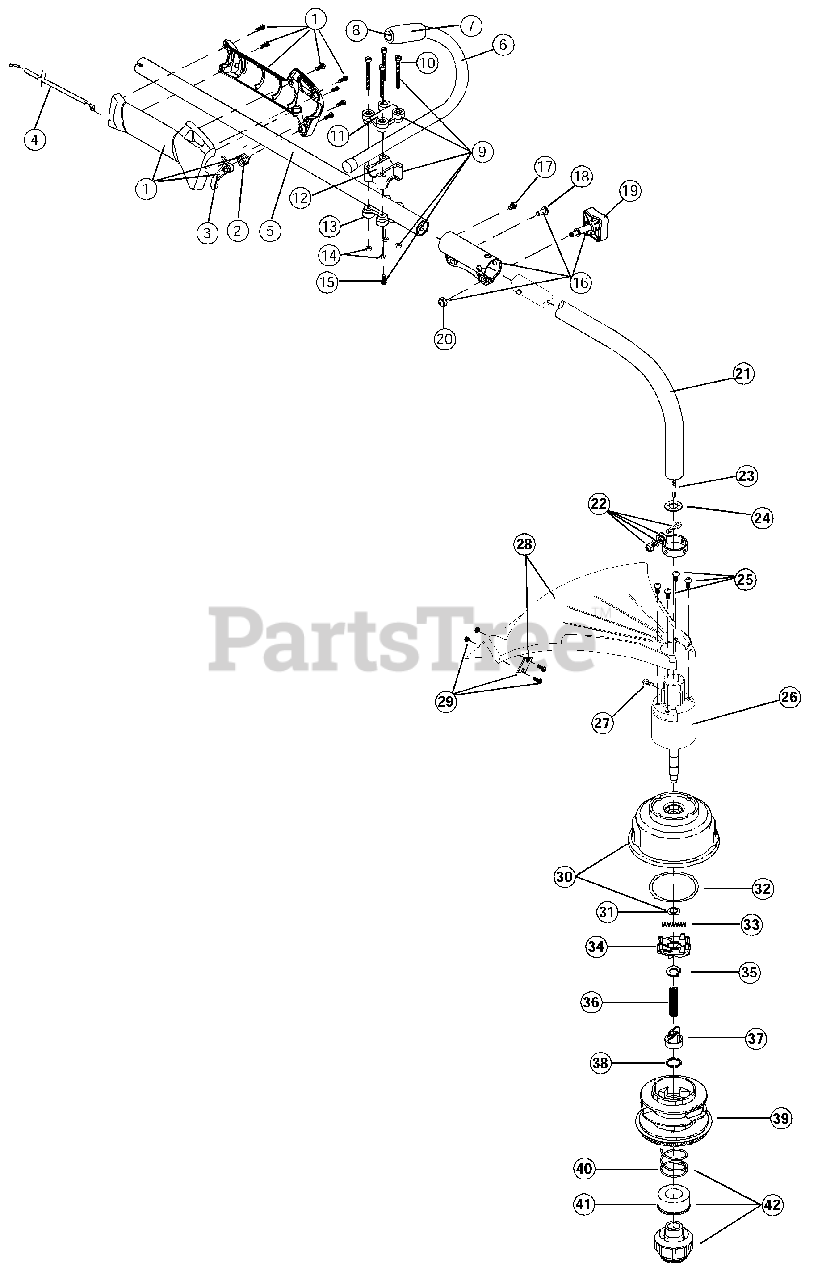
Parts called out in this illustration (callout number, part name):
1	Throttle Housing and Trigger Assembly
2	Throttle Trigger Spring
3	Throttle Trigger
4	Throttle Cable Assembly
5	Upper Drive Shaft Housing Assembly
6	J-Handle Assembly
8	Tube Closure
9	Handle Bracket Assembly
11	Upper Handle Clamp
12	Middle Handle Clamp
13	Lower Handle Clamp
15	Anti-Rotation Screw
16	Click-Link Coupler
19	Adjustment Knob
20	Knob Retaining Nut
21	Lower Drive Shaft Housing Assembly
22	Lower Clamp Assembly
23	Lower Flexible Drive Shaft
24	Palnut
25	Shield Mounting Screw
26	Bushing Housing Assembly
27	Anti-Rotation Screw
28	Shield and Blade Assembly
29	Blade Assembly
30	Outer Spool and Eyelet Assembly w/Retainer
31	Retainer
32	Thrust Washer
33	Small Spring
34	Slider
37	Plunger
39	Inner Reel
40	Large Spring
41	Foam Seal
42	Bump Head Knob Assembly w/Spring & Foam Seal
